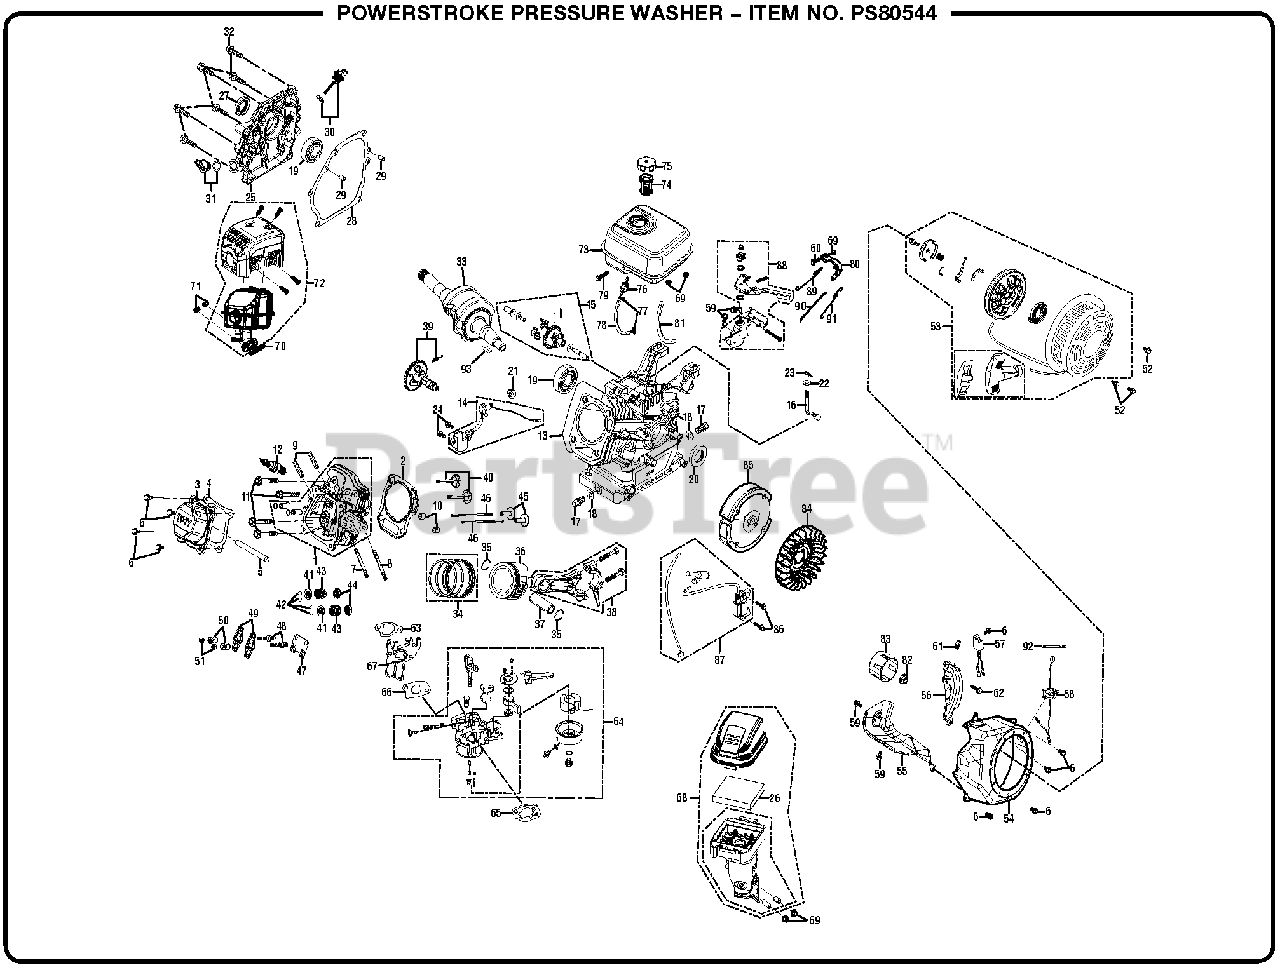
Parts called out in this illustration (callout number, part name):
1	Cylinder Head Assembly
2	Cylinder Head Gasket
3	Cylinder Head Cover Assembly
4	Cylinder Head Cover Gasket.
11	Cylinder Head Bolt
13	Crankcase Assembly
14	Engine Oil Sensor
15	Governor Gear Assembly
25	Crankcase Cover
28	Crankcase Gasket
30	Oil Dipstick Assembly
31	Engine Oil Plug Assembly
33	Crankshaft Assembly
34	Piston Ring Assembly
35	Piston Pin Clip
36	Piston Assembly
39	Camshaft Assembly
41	Valve Spring Seat
42	Valve Lock Clip
47	Lifter Stopper Plate Assembly
48	Valve Adjusting Bolt
50	Valve Adjusting Nut
53	Recoil Starter Assembly
55	Cylinder Body Shroud
58	Stop Engine Switch Assembly
60	Governor Support Bolt
63	Carburetor Insulator Gasket
64	Carburetor Assembly
65	Air Cleaner Gasket
66	Carburetor Gasket
67	Carburetor Insulator Plate
72	Muffler Assembly
75	Fuel Tank Cover
76	Fuel Tank Oil Outlet Assembly
80	Governor Support Assembly
85	Flywheel Assembly
87	Ignition Coil
88	Throttle Control Assembly
89	Governor Spring
91	Throttle Valve Return Spring
